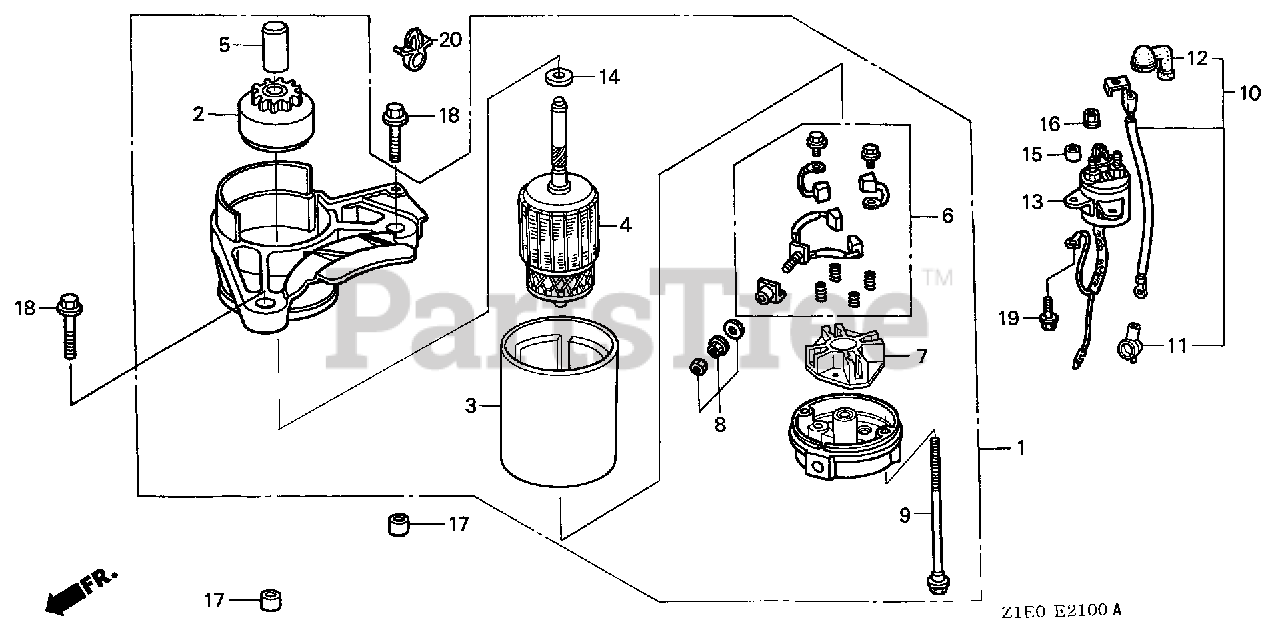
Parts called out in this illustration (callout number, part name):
1	MOTOR ASSY., STARTER
2	DRIVE ASSY.
5	STOPPER SET, PINION
6	BRUSH SET
7	HOLDER, BRUSH
8	NUT SET, TERMINAL
9	BOLT, THROUGH
10	WIRE, MAGNETIC SWITCH
11	COVER, STARTER TERMINAL
12	COVER, MAGNETIC SWITCH TERMINAL
13	SWITCH ASSY., STARTER MAGNETIC
14	WASHER, THRUST
15	COLLAR (6.5X11X10)
16	NUT-WASHER (6MM)
17	PIN, DOWEL (10X12)
18	BOLT, FLANGE (8X35)
19	BOLT, FLANGE (6X25)
20	CLIP, WIRE HARNESS
